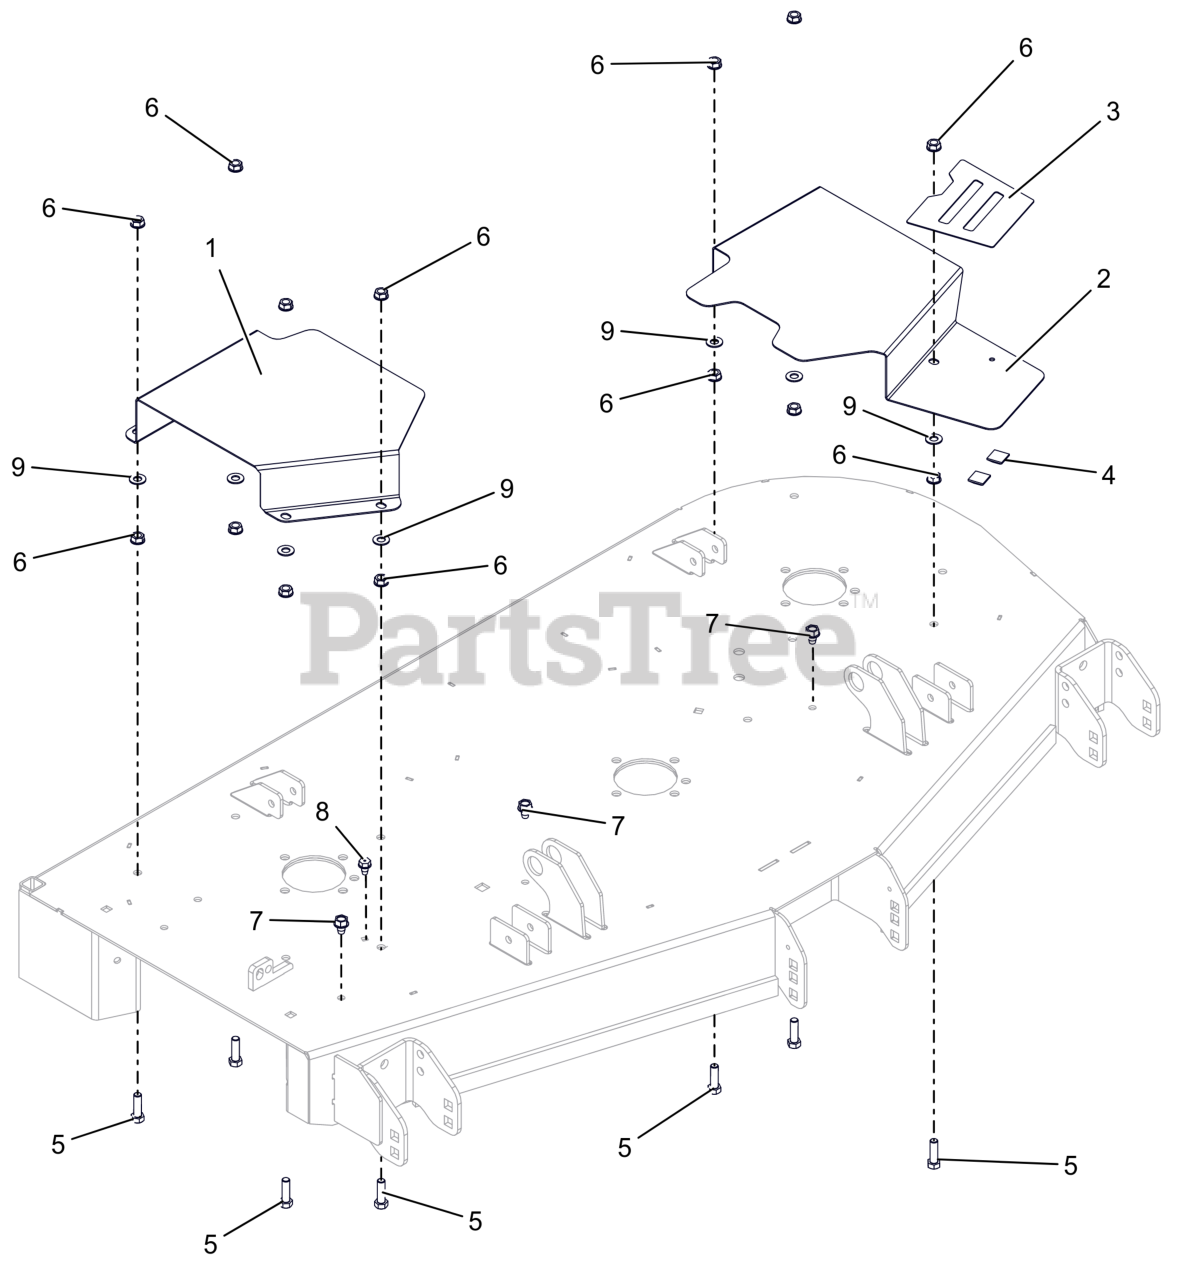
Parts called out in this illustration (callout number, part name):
1	COVER, BELT 52" & 60" RIGHT
2	COVER, BELT 52" LEFT
3	GRIP, TAPE 52-60 BELT COVER
5	BLT, HEX .38-16X1.25 G5 ZCC
6	NUT, SPNLK-FLG .38-16 G5 ZCC
7	SCR,TAP .375-16X.50 HWH TR ZCC
8	SCR,TAP .312-18X.50 HWH TR ZCC
9	WSHR,FLT .406X.812X.065 ZCC
